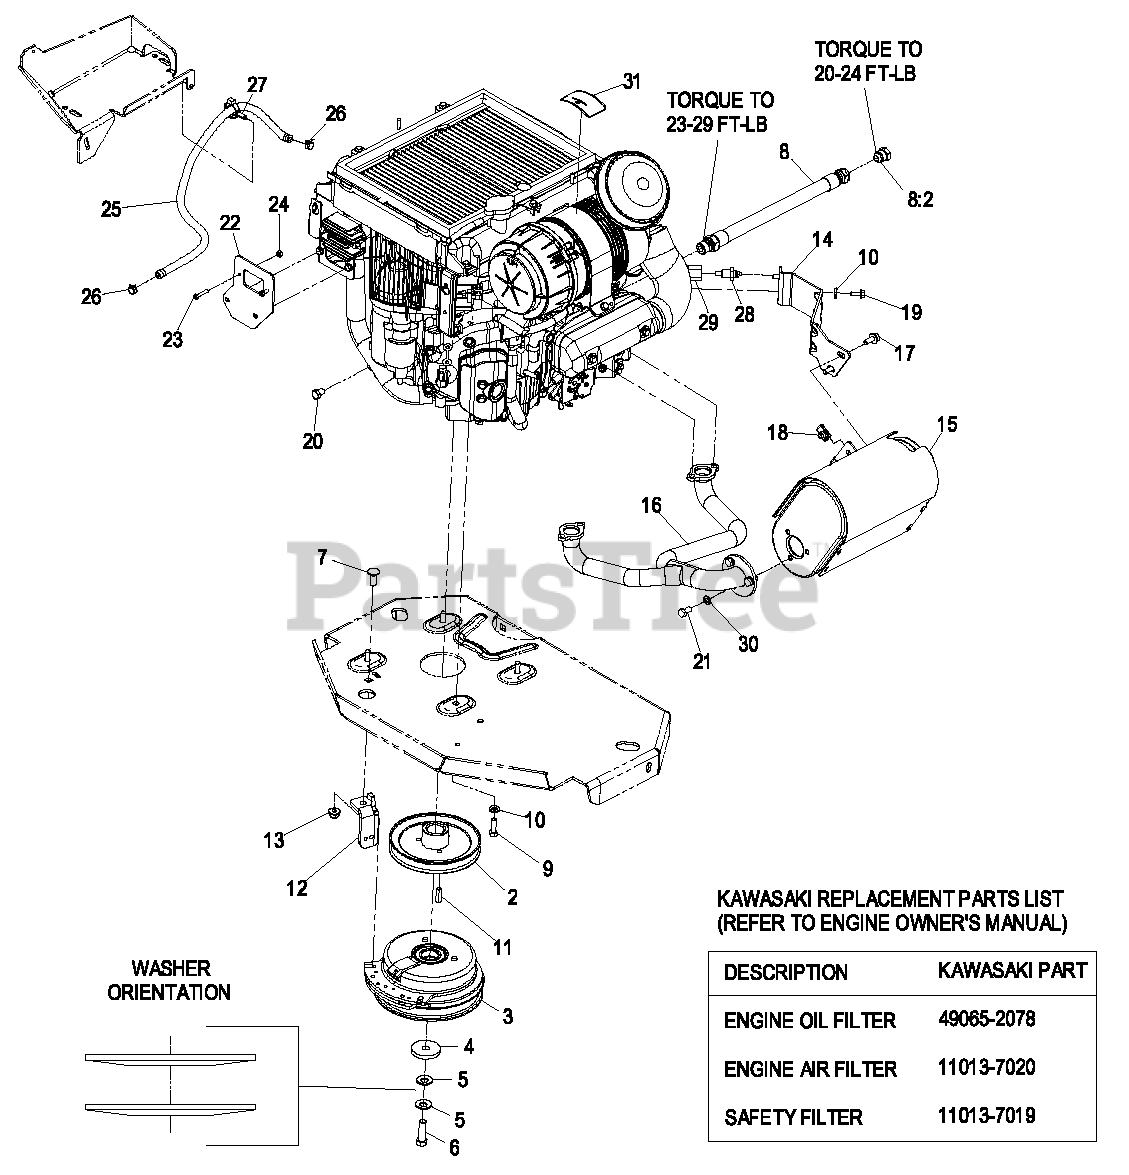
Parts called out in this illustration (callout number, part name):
2	SHEAVE
4	WASHER-CLUTCH
5	WASHER-SPRING
6	SCREW-HH 7/16-20 X 1 1/2 W/LOCTITE
7	SCREW-CARR
9	SCREW-HH
10	WASHER-SPRING
12	ANCHOR-CLUTCH
13	NUT-HF, NI
14	BRACKET,MUFFLER 26LKA
15	MUFFLER-ENGINE
16	MANIFOLD,EXHAUST 26LKA
17	SCREW-HHF
19	SCREW-HHF
20	SCREW-HH
21	SCREW-HH
22	PLATE,RECTIFIER MOUNT, LK
24	NUT-LOCK, NI
25	HOSE-FUEL
26	CLAMP-HOSE
27	CLAMP-HOSE
28	SENDER-TEMPERATURE
30	WASHER-LOCK
31	DECAL,SHELL COOLANT
